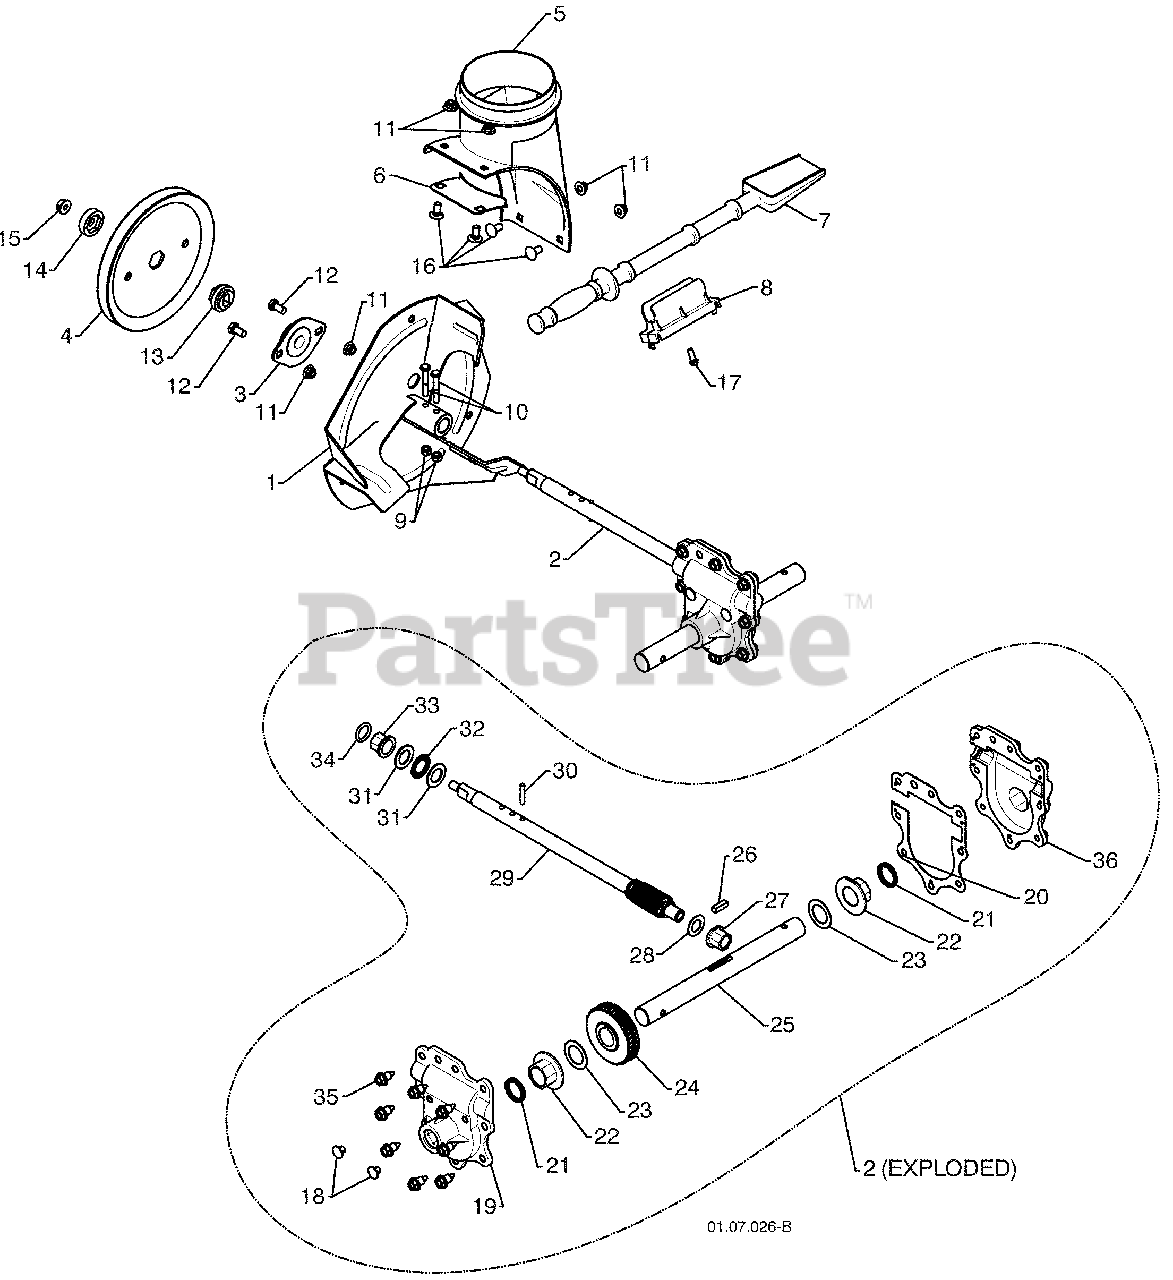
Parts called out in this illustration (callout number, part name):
1	IMPELLER
2	GEARBOX ASSEMBLY
4	IMPELLER PULLEY
5	DISCHARGE BASE
6	CORNER BRACKET
7	CLEAN OUT TOOL
9	NUT 1/4-20
10	SCREW 1/4-20 X .625
11	NUT 5/16-18
12	SCREW 5/16-18 X .625
13	IMPELLER HUB
14	IMPELLER SLEEVE
15	NUT 3/8-16
16	CARRIAGE BOLT
17	SCREW 13-16 X .625
18	PLUG
19	GEARBOX COVER RH
21	SEAL
22	BEARING
23	THRUST WASHER 1.00
24	WORM GEAR
25	AUGER SHAFT
26	SQUARE KEY
27	BEARING
28	THRUST WASHER
29	IMPELLER SHAFT
30	ROLL PIN
31	THRUST WASHER
32	THRUST BEARING
35	SCREW 5/16-18 X .750
36	GEARBOX COVER LH
